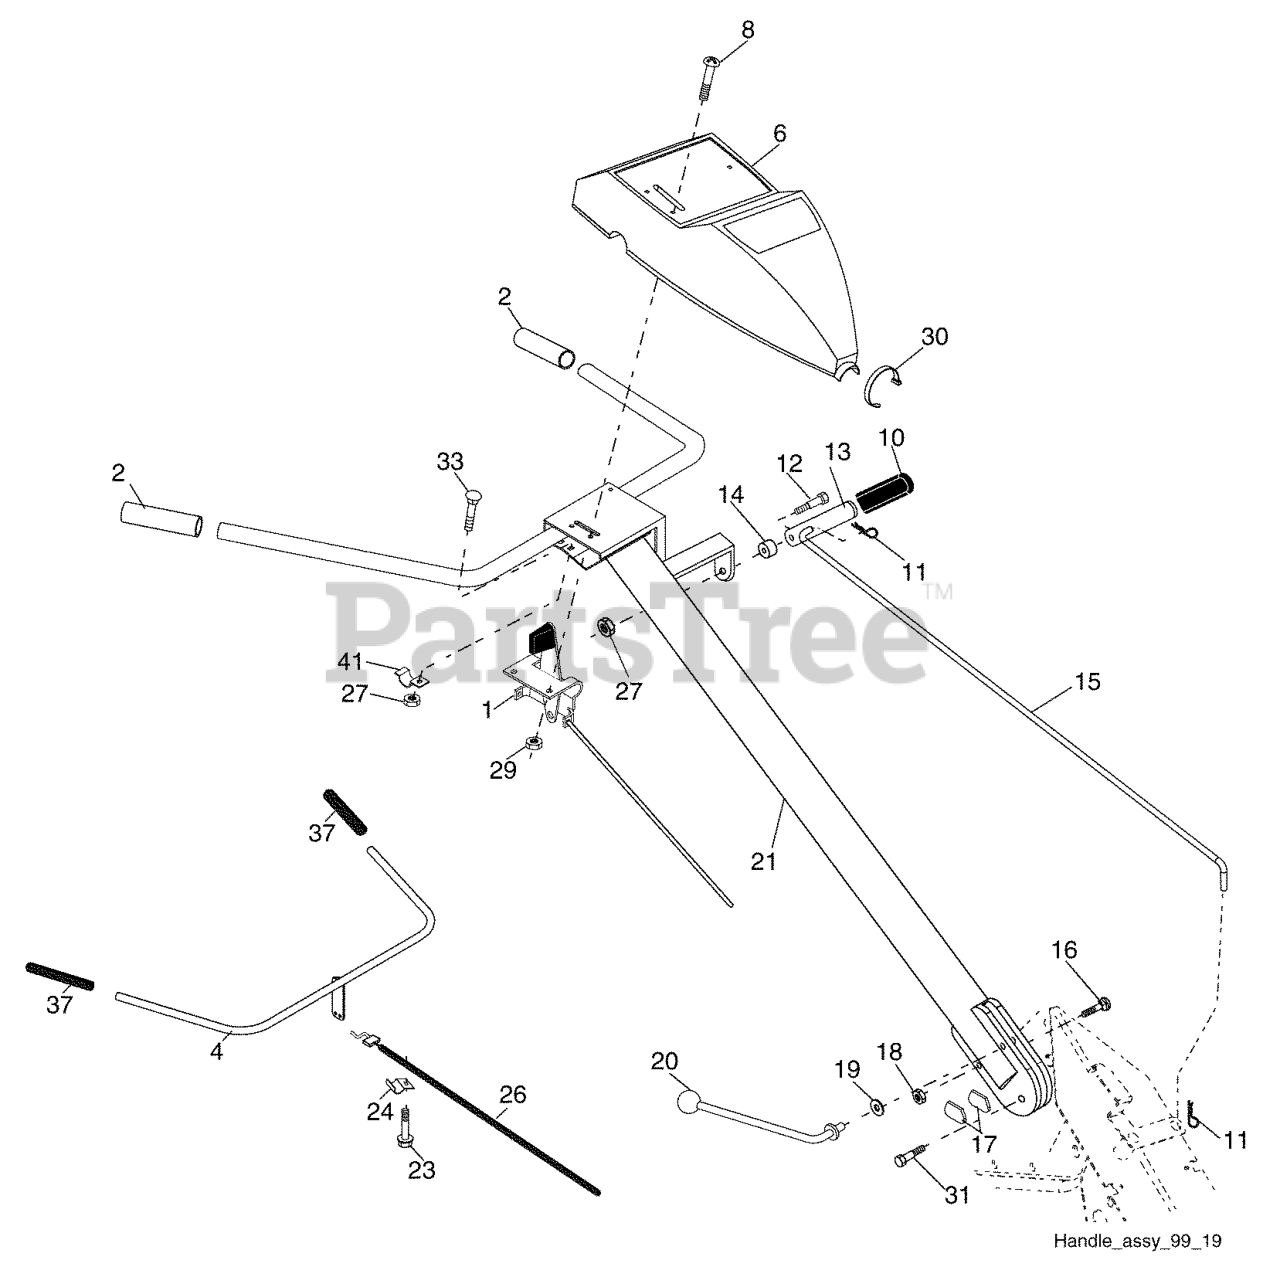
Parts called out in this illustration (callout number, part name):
1	THROTTLE.CONTROL.RT.INTEK.50
2	GRIP.HANDLE.BLACK
4	CONTROL BAR ASSY
6	RP CONTROL PANEL
8	SCREW.PNHD.10-24
10	GRIP T
11	RETAINER M
12	SHOULDER BOLT ST
13	HANDLE.SHIFT.TILLER
14	GROMMET.RUBBER.CRT.TILLER
15	SHIFT ROD CRT
16	BOLT D
17	LOCK.HANDLE.CRT
19	WASHER CRT
20	LEVER.LOCK.CRT
21	REPL BY 532 1805-17
23	TAPPING SCREW
24	CONDUIT.CLIP.PLATED
26	CABLE.CLUTCH
27	NUT T
29	NUT **
30	TIE CABLE CRT
31	BOLT.PIVOT
33	BOLT
37	GRIP BAR CRT(1)
41	CLAMP.BAR.CRT.BLACK
